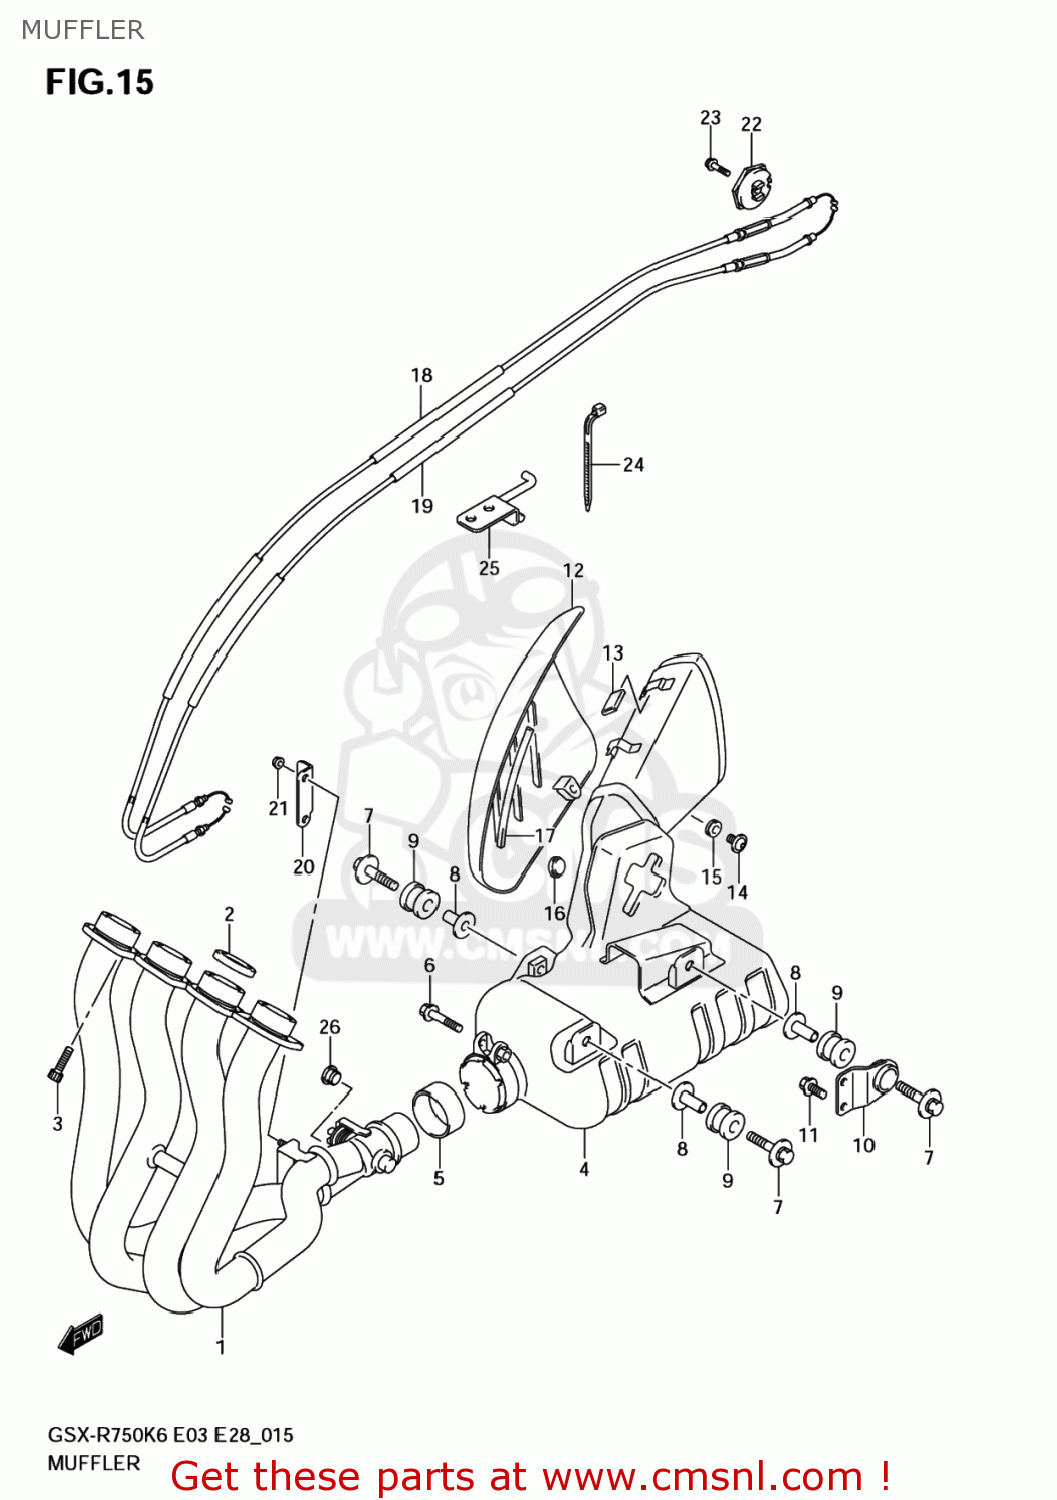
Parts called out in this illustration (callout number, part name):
1	PIPE,EXHAUST
2	GASKET,EXHAUST PIPE
3	BOLT
4	MUFFLER
5	CONNECTOR,MUFFLER
6	BOLT(8X40)
7	BOLT(8X45)
8	SPACER (8.6X12
9	CUSHION
10	BRACKET,CHAMBER SPRT
11	BOLT
12	COVER COMP,MUF
13	GROMMET
14	SCREW(6X12)
15	CUSHION
16	CUSHION
17	SEAL(L:520)
18	CABLE,EXH VALV
19	CABLE,EXH VALV
20	BRACKET,EXHAUST VALVE CABLE
21	NUT
22	PULLEY CONTROL
23	BOLT
24	CLAMP(L:190)
25	BRACKET,EXHAUST VALVE CABLE
26	PLUG
